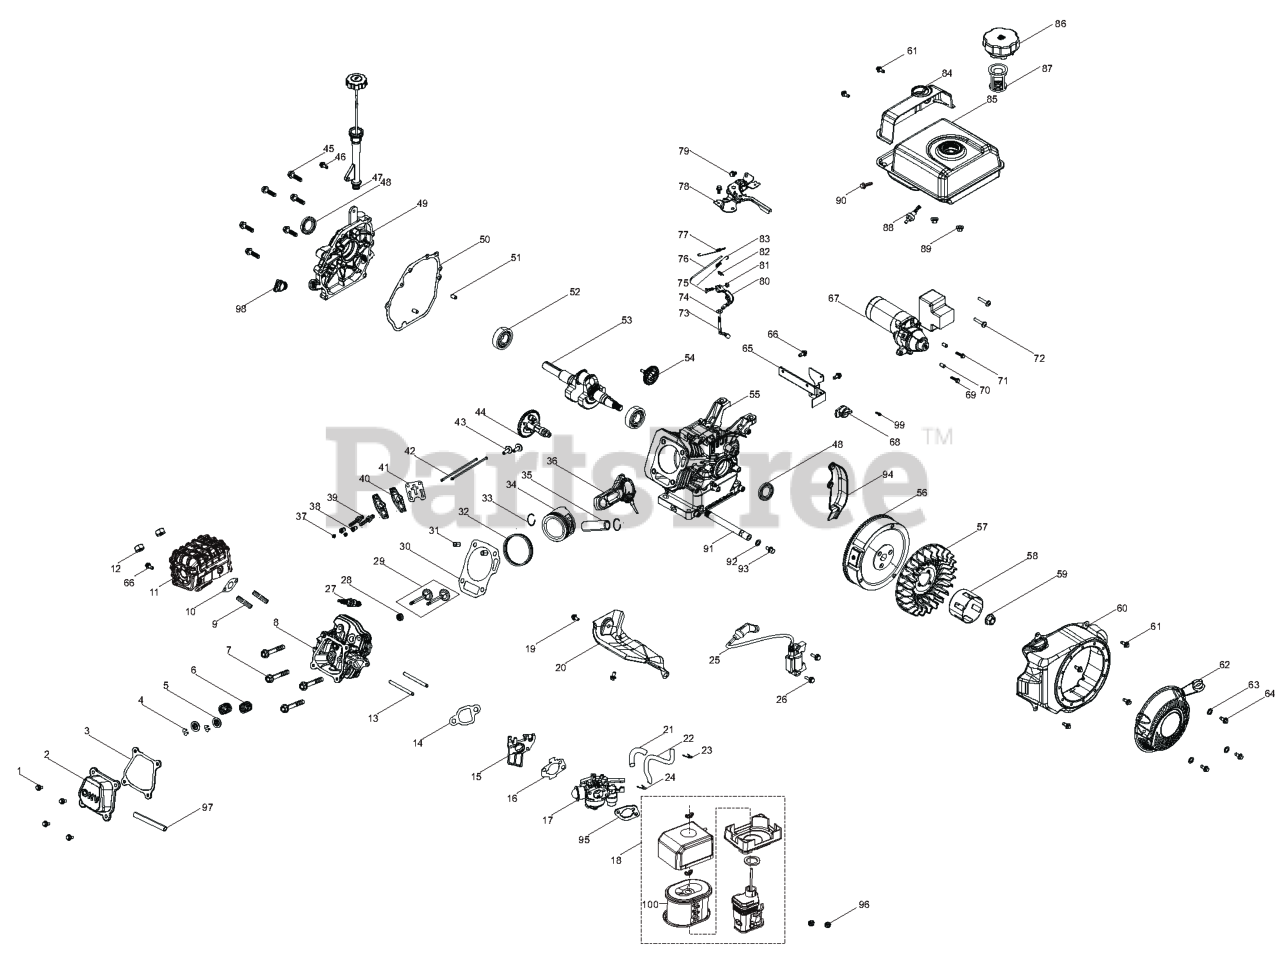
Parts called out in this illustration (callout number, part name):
1	BLT, HEX-FLG M6X12
2	COVER, VALVE
3	GASKET, VALVE COVER
4	CLAMP, VALVE LOCK
5	SEAT, VALVE SPRING
6	SPRING, VALVE
7	CYLINDER HEAD BOLT
8	CYLD, HEAD SUBASM
9	BLT, STUD
10	GASKET, EXHAUST OUTLET
11	ASM, MUFFLER
12	TYPE 1 HEXAGON NUT
13	BLT, STUD (BM=20)
14	GASKET, CARBURETOR INSULATOR
15	PLATE, CARBURETOR INSULATOR
16	CARBURETOR SEAL GASKET
17	ASM, CARBURETOR
18	ASM, AIR CLEANER
19	BOLT, M6X10 HEX FLANGE
20	SHROUD, CLYD BODY
21	JACKET, RUBBER
22	TUBE, FUEL
23	PIPE CLAMP
24	PIPE CLAMP
25	COIL, IGNITION
26	BLT, HEX-FLG M6X25X1
27	SPARK PLUG - PLATINUM
28	GUIDE, SEAL
29	VALVE, SET
30	GASKET, CYLD HD
31	PIN, POSITION
32	ASM, PISTON RING
33	CLIP, PISTON PIN
34	PISTON
35	PIN, PISTION
36	ROD, CONNECTING
37	NUT, VALVE LOCK
38	NUT, VALVE ADJUSTING
39	ROCKSHAFT BOLT
40	VALVE, ROCKER
41	PLATE, SUBASM LIFTER STOPPER
42	VALVE, LIFTER
43	TAPPET, VALVE
44	ASM, CAMSHAFT
45	BLT, HEX-FLG M8X32X1.25
46	HEX, SOCKET-FLG M6X20
47	SUBASM, OIL DIPSTICK
48	SEAL, OIL
49	COVER, CRANKCASE
50	GASKET, CRANKCASE
51	POSITION PIN - TYPE A
52	BRG-BALL, DEEP GROOVE
53	ASM, CRANKSHAFT
54	ASM, GEAR GOVERNOR
55	SUBASM, CRANKCASE
56	SUBASM, FLYWHEEL
57	IMPELLER
58	PULLEY, STARTER
59	NUT, FLYWHEEL
60	SHROUD
61	BLT, HEX-FLG M6X12
62	ASM, STARTER RECOIL
63	WSHR-FL, GR A
64	BOLT, M6X8 HEX FLANGE
65	SUBASM, CONTROL BOX SUPPORT
66	BLT, HEX-FLG M6X14X1
67	STARTING MOTOR ASSEMBLY
68	BRKT, ENGINE STOP MTG SWITCH
69	BLT, HEX-FLG M6X25X1
70	POSITION PIN - TYPE A
71	BLT, HEX-FLG M6X35X1
72	SCREW, PAN HEAD M4X55X0.7
73	ARM, GOVERNOR
74	FLAT WASHER - GRADE A
75	BOLT, GOVERNOR SUPPORT
76	ROD, GOVERNEOR
77	SPRG, GOVERNOR
78	ASM, CONTORL THROTTLE
79	BOLT, M6X10 HEX FLANGE
80	ASM, GOVERNOR BRACKET
81	HEXAGON NUT WITH FLANGE
82	PIN, COTTER
83	SPRING, THROTTLE VLV RETURNING
84	FUEL TANK PLATE
85	TANK, FUEL
86	CAP, FUEL
87	STRAINER, FUEL
88	OUTLET WITH FILTER
89	HEXAGON NUT WITH FLANGE
90	BLT, HEX-FLG M6X32X1
91	TUBE, OIL DRAIN
92	FLAT WASHER - GRADE A
93	BOLT, DRAIN PLUG
94	SHEILD, LOWER
95	GASKET, AIR CLEANER SEAL
96	HEXAGON NUT WITH FLANGE
97	TUBE, BREATHER
98	ASM, ENGINE OIL PLUG
99	BLT, HEX-FLG M6X14X1
100	AIR CLEANER ELEMENT
NS	KIT, HIGH ALT 3K-6K FT 212CCAS
NS	KIT, HIGH ALT 6K-8K FT 212CCAS
